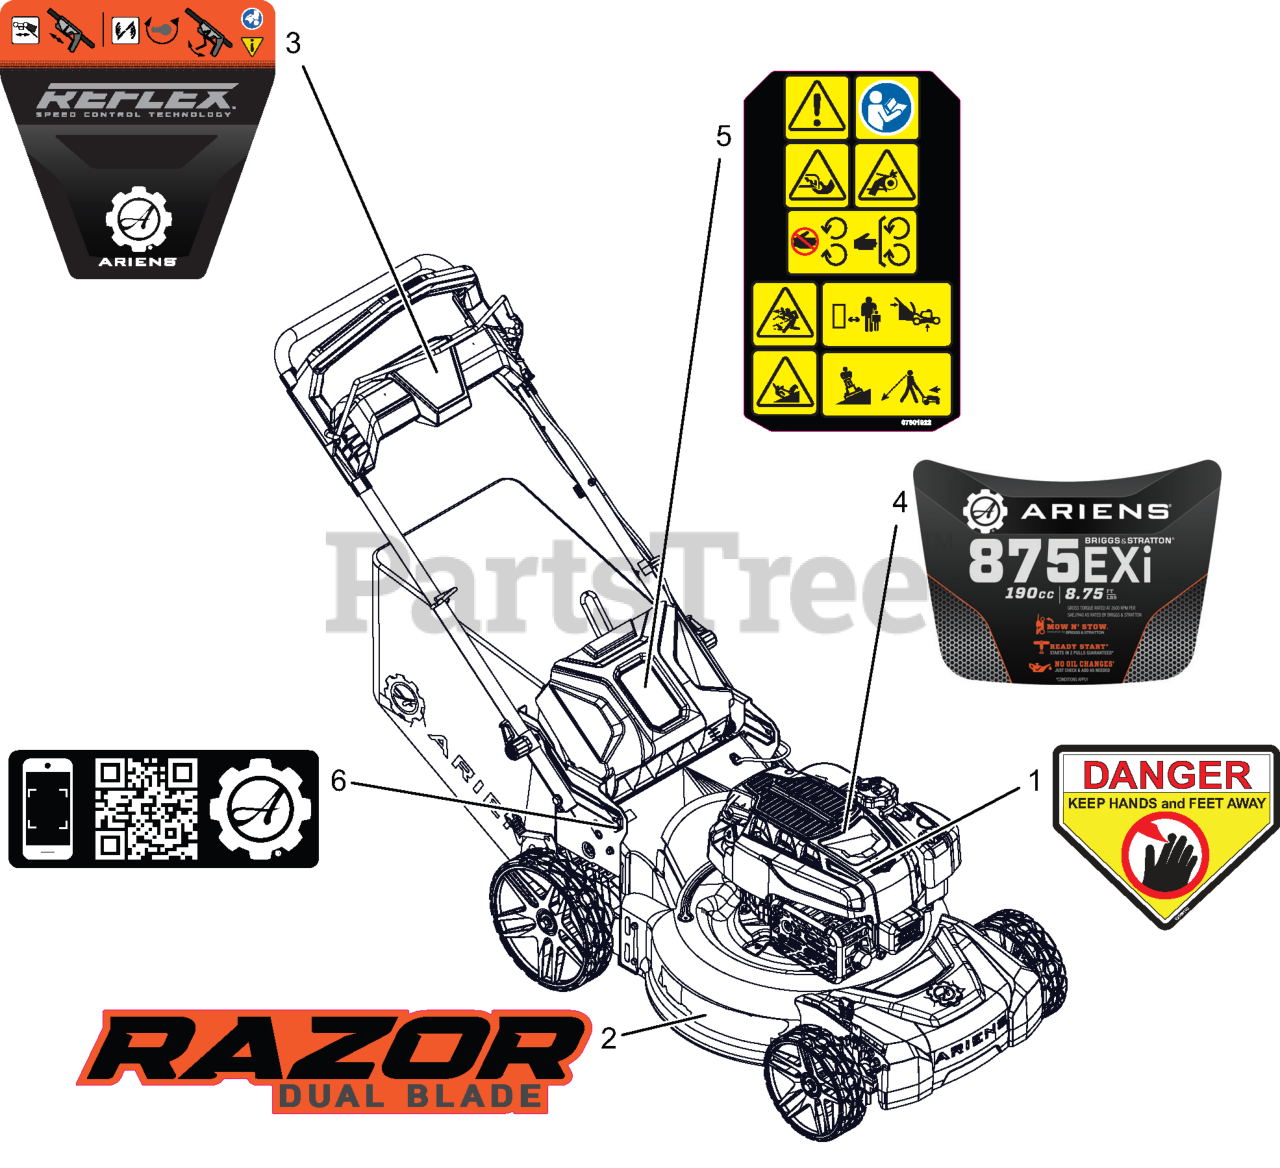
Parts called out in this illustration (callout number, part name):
1	DECAL, DANGER
2	DECAL, ARIENS RAZOR DUAL BLADE
3	DECAL, ARIENS REFLEX CONTROL
4	DECAL, ENGINE 190CC
5	DECAL, MAIN SAFETY - WALK
6	DECAL, RAZOR QR
